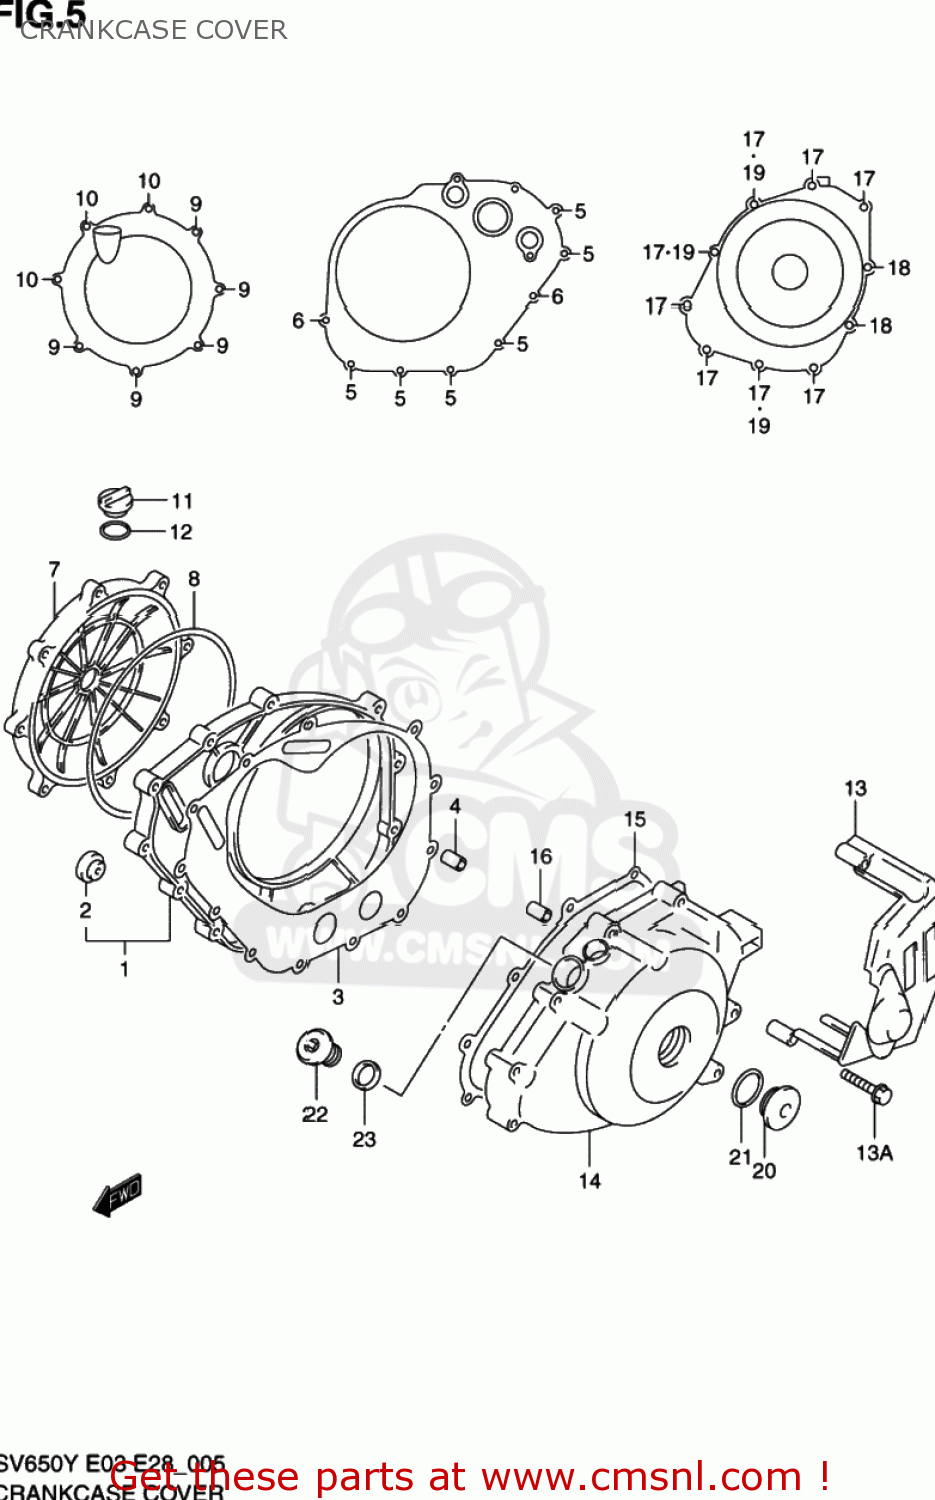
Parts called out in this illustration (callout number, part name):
1	COVER,CLUTCH INNER
2	LENS,OIL LEVEL CHECK
3	GASKET,CLUTCH COVER INNER (NAS)
4	PIN
5	BOLT(6X30)
6	BOLT(6X40)
7	COVER,CLUTCH OUTER
8	O-RING,CLUTCH COVER,OUTER
9	BOLT(6X25)
10	BOLT(6X55)
11	PLUG
12	O RING(D:3.1,ID:16.8)
13	COVER,ENGINE SPROCKET
13A	BOLT
14	COVER,MAGNETO
15	GASKET,MAGNETO COVER (NAS)
16	PIN
17	BOLT
18	BOLT
19	GASKET(5.8X13X1.2) (NAS)
20	PLUG
21	O RING(D:3.1,ID:22.7)
22	PLUG,16X8
23	GASKET(16X22X2) (NAS)
